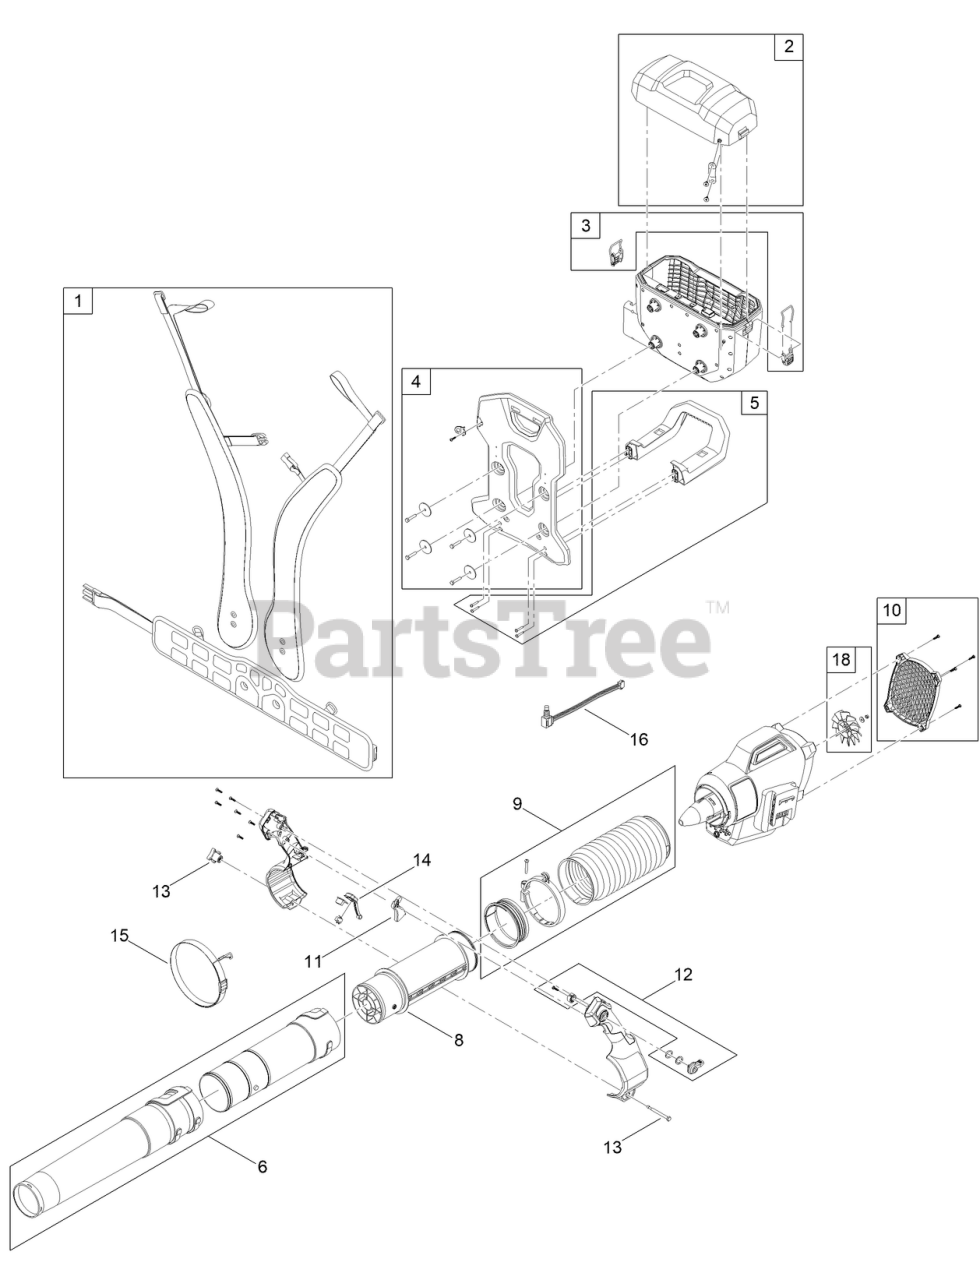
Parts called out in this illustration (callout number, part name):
1	HARNESS-SHOULDER/HIP STRAPS KIT
2	COVER-BATTERY HOUSING
3	LATCH-BATTERY HOUSING
4	PLATE-BATTERY HOUSING MOUNT
5	BRACE-BACKPACK PLATE
6	AIR OUTLET TUBE KIT
8	TUBE-PISTOL HANDLE SLIDE
9	TUBE-FEXIBLE/CORIGATED
10	COVER-AIR INLET
11	TRIGGER-PISTOL HANDLE
12	LEVER-SPEED LOCK ASM
13	KNOB-PISTOL HANDLE ADJUSTMENT
14	BUTTON-TURBO SPEED
15	STRAP-BLOWER
16	SWITCH-SPEED CONTROL
18	FAN-BLOWER
